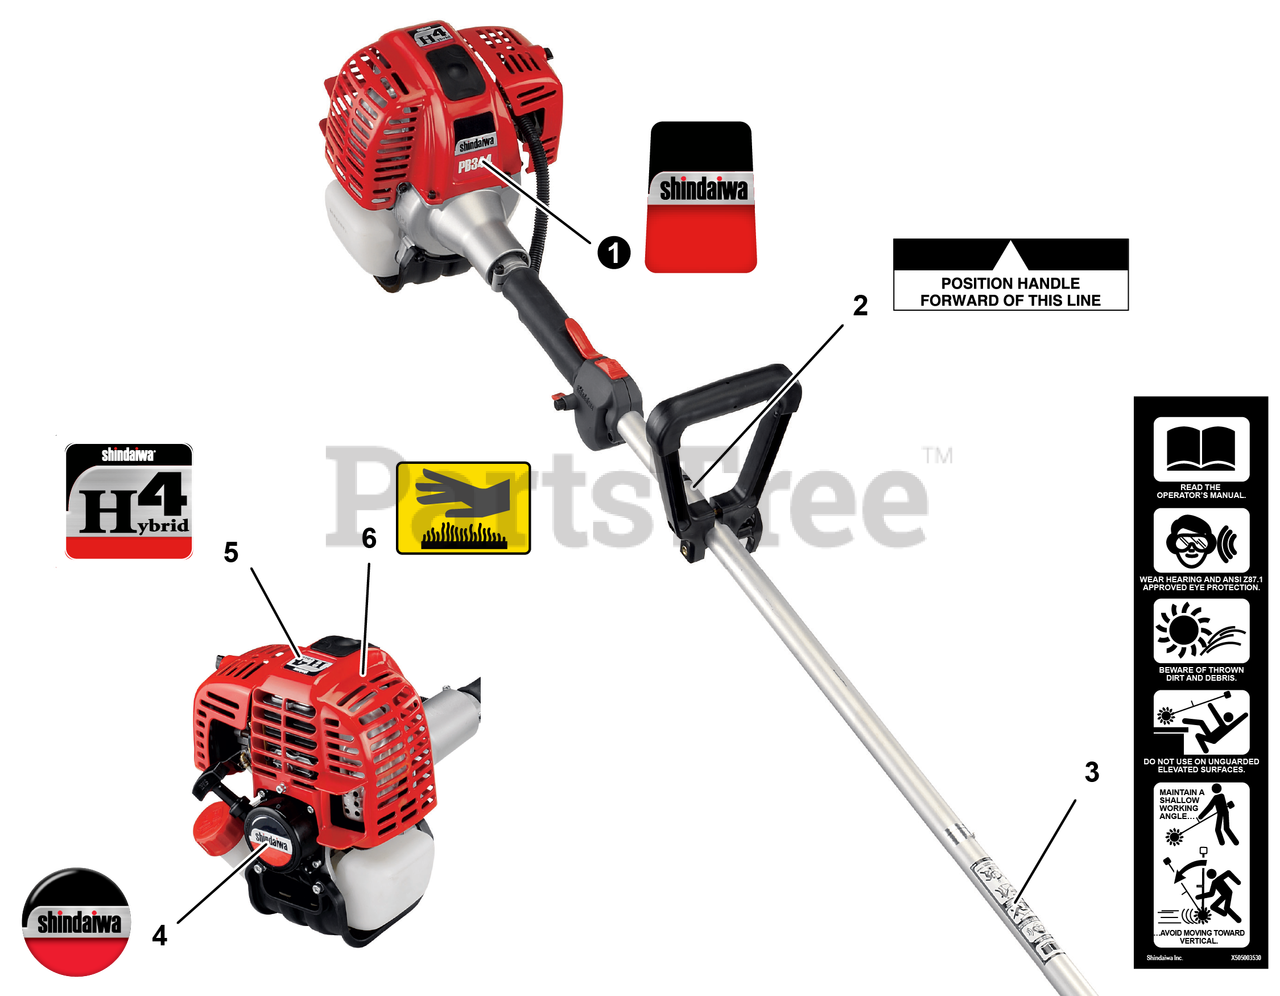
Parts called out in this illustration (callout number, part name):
1	LABEL - MODEL PS344
2	LABEL, HANDLE
3	LABEL, CAUTION
4	LABEL, RECOIL STARTER
5	LABEL, shindaiwa H4
6	LABEL, CAUTION - HOT
